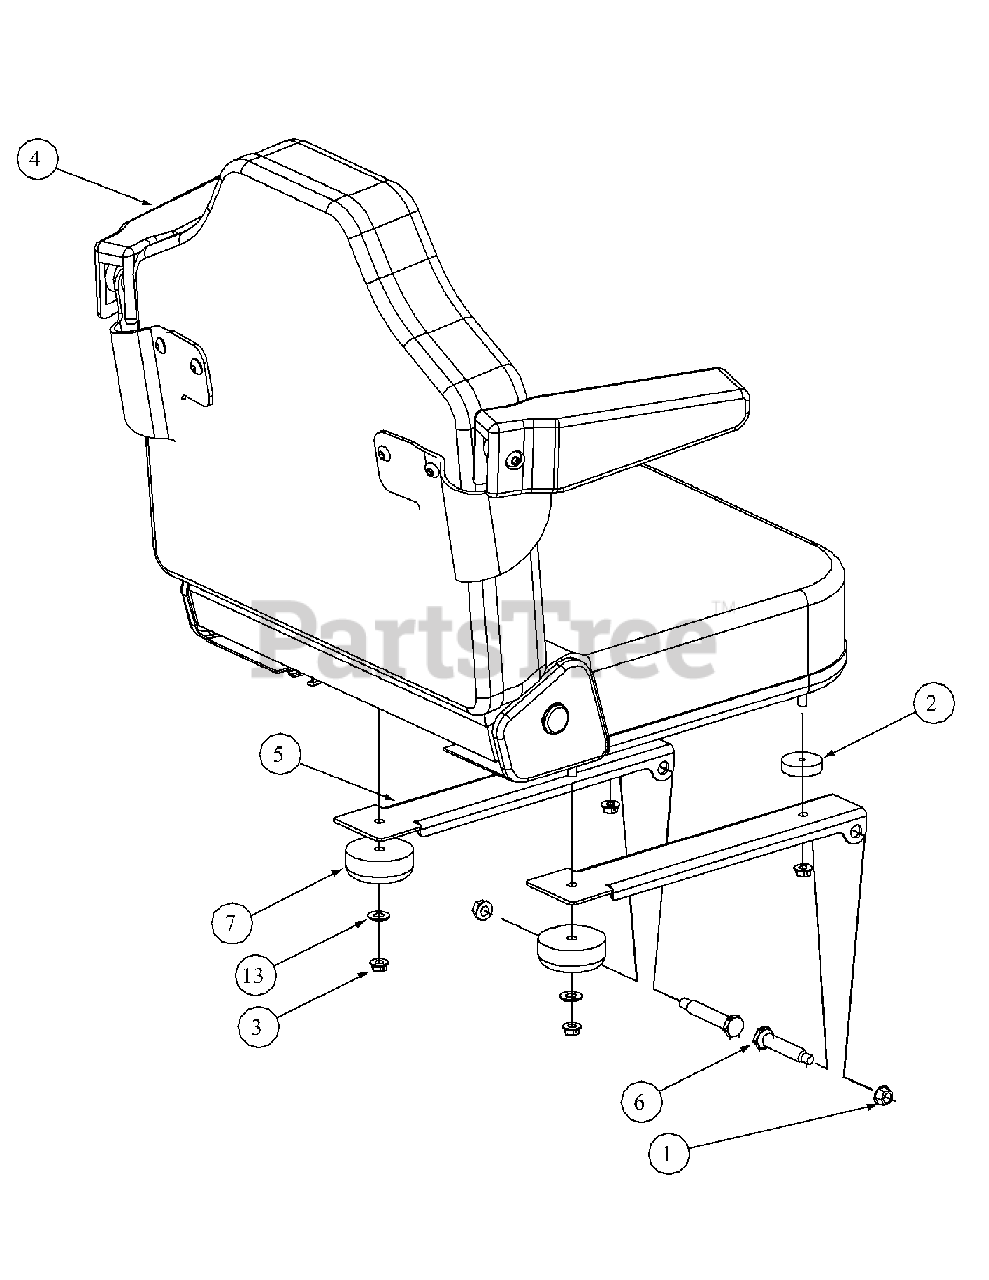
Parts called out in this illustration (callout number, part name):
1	Nut, Hex 3/8-16 Flange Lock
2	Spacer, 0.345 ID x 1.50 OD x .41
3	Lock Nut, Hex Flange, 5/16-18
4	Adjustable Seat, Black embossed,
5	Mounting Bracket, Seat
6	Shoulder Screw, .50x2.345, 3/8-16
7	Grommet, 2.5 OD x 1.0 Long
13	Washer
